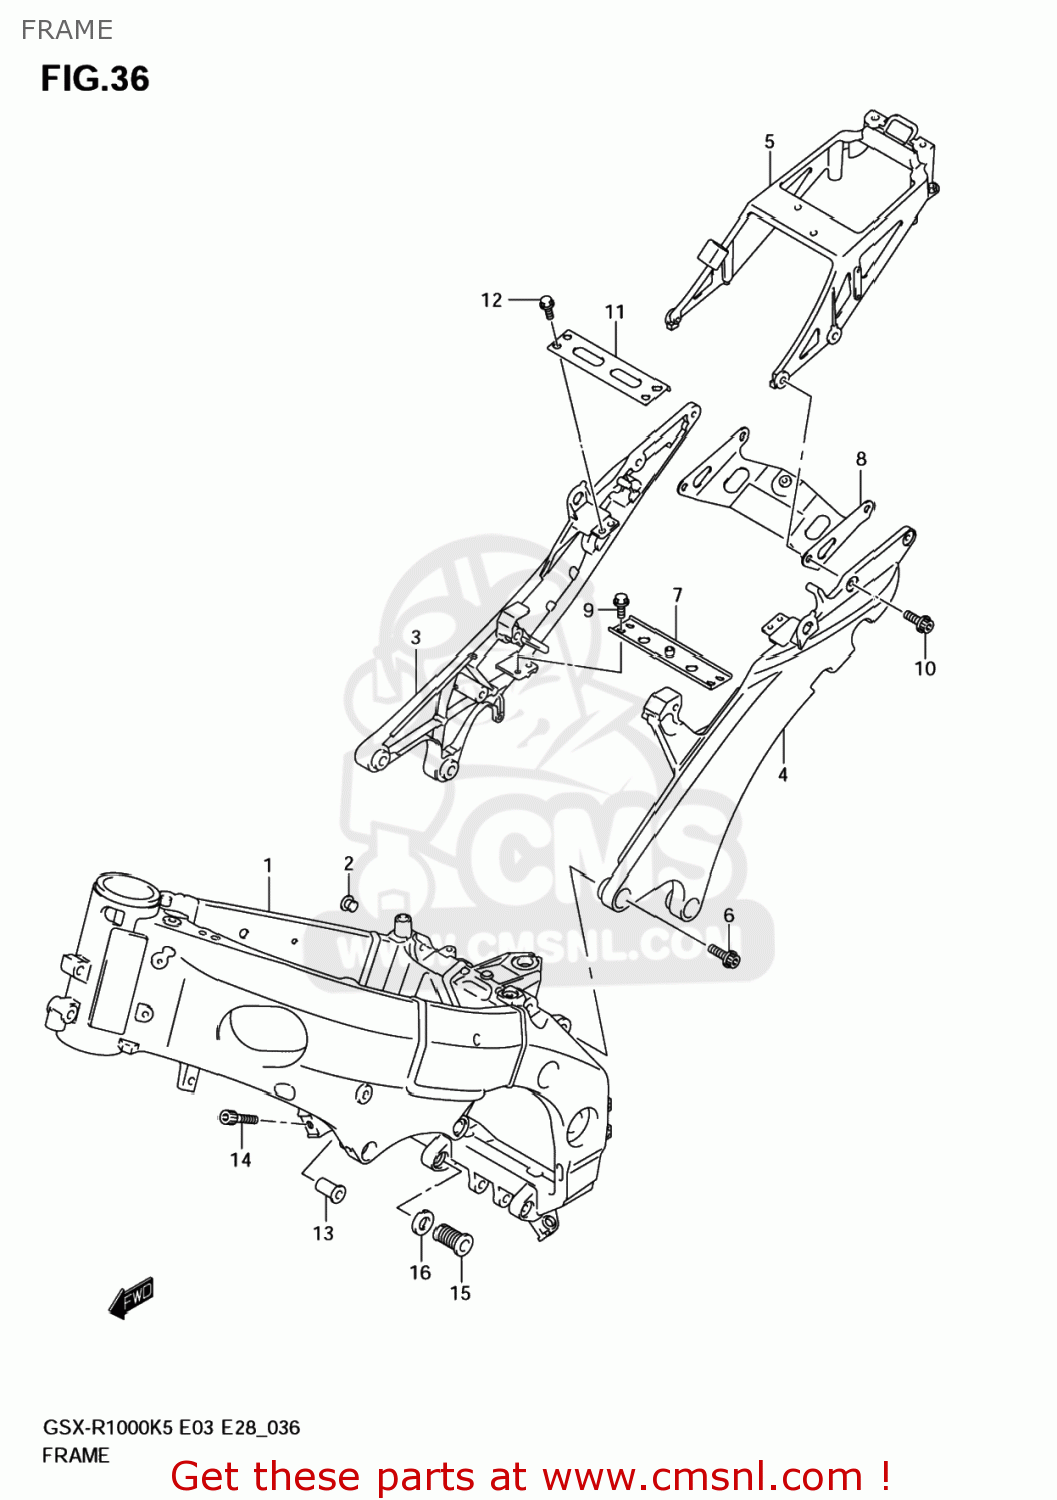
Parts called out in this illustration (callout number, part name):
1	FRAME COMP
2	CAP,TANK RAIL
3	RAIL,SEAT,R
4	RAIL,SEAT,L
5	BRACKET,PILLIO
6	BOLT,SEAT RAIL
7	BRIDGE,SEAT RAIL FR
8	BRIDGE,SEAT RAIL RR
9	BOLT 6X12
10	BOLT
11	BRIDGE,SEAT RAIL UPR
12	BOLT 6X12
13	SPACER,ENGINE MOUNTING
14	BOLT
15	BOLT,CRANK CASE ADJUST
16	NUT,ADJUST BOLT
